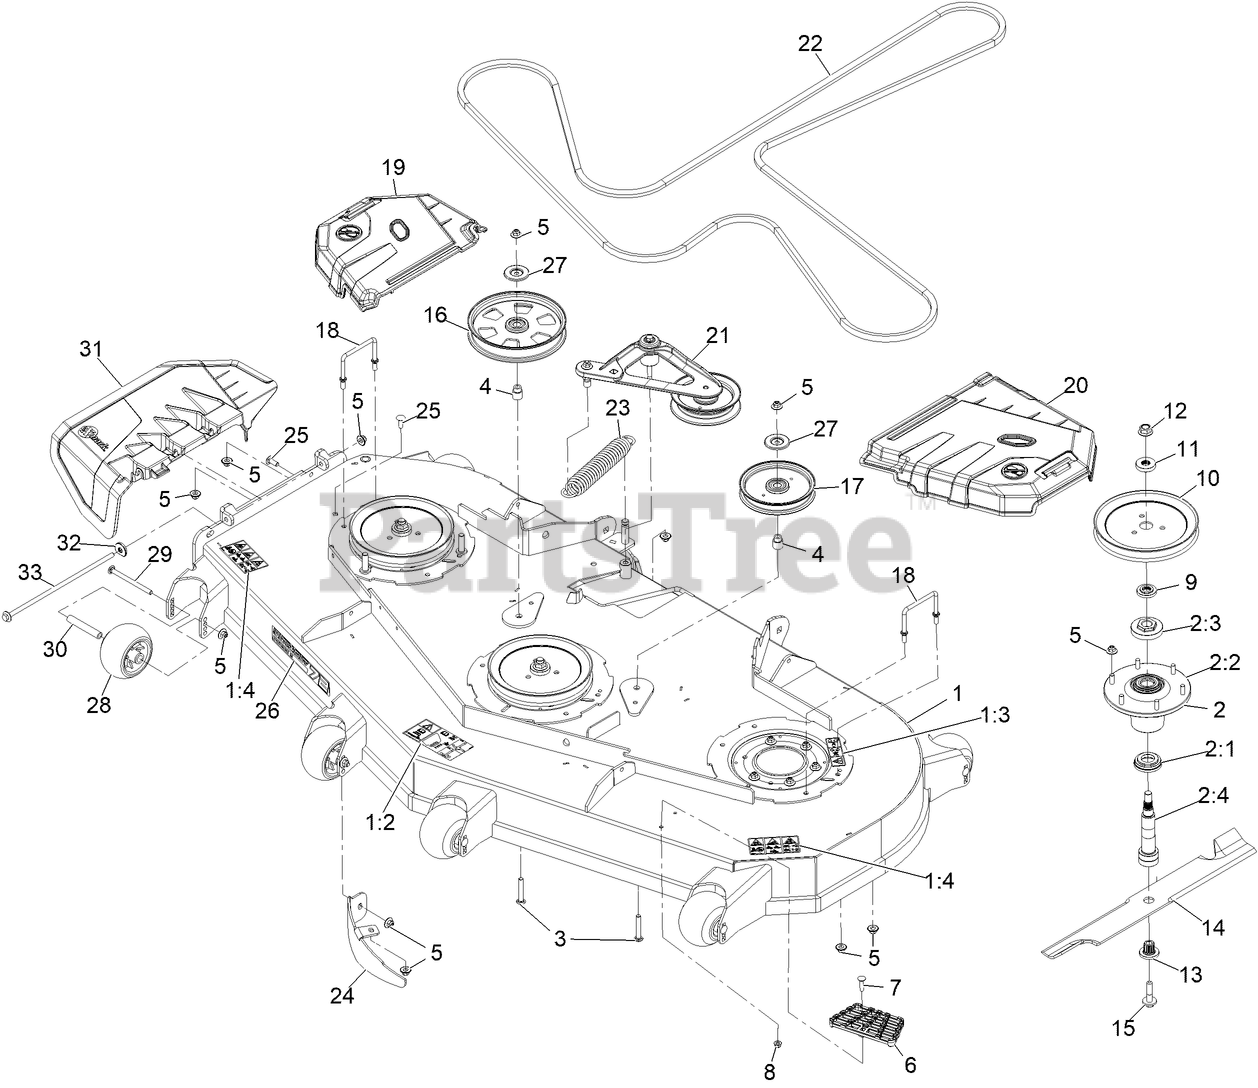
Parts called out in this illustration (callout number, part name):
1	ASM, Deck W/Decals 72
1:2	Decal-Anti-Scalp-Belt Routing
1:3	DECAL-COVER, MISSING
1:4	DECAL-DANGER THROWN OBJECTS
2	ASM,SPINDLE HOUSING
2:1	GUARD,BOTTOM
2:2	ASM,CUTTER HOUSING
2:3	NUT, SPINDLE 7/8-14
2:4	SPINDLE,DOUBLE SPLINE
3	SCREW-CARR
4	BUSHING-IDLER
5	Nut-Nyloc 3/8-16 Flg
6	STEP-DECK
7	Bolt-Carriage 5/16-18 X 1 1/4
8	NUT-HF, NI
9	SPACER,SPLINED STEPPED
10	SHEAVE,BLADE DRIVE 9.00
11	SPACER,SPLINED
12	NUT-FLANGE, CENTERLOCK
13	BUSHING,SPLINED
15	SCREW,SEMS 1/2-20 X 2.19
16	PULLEY-IDLER, FLAT
17	Idler-Pulley, Flat
18	WIREFORM-COVER
19	SHIELD, RT
20	SHIELD, LT
21	ASM-IDLER, DECK
23	SPRING-EXTENSION
24	BAFFLE-DOGLEG, LZ72
25	SCREW-CARR
26	DECAL, 726
27	SHIELD-DUST
28	ROLLER-SCALP, ANTI
29	BOLT-CARR
30	SPACER-AXLE
31	Chute-Deck Discharge
32	Retainer, Chute
33	Pin, Chute
